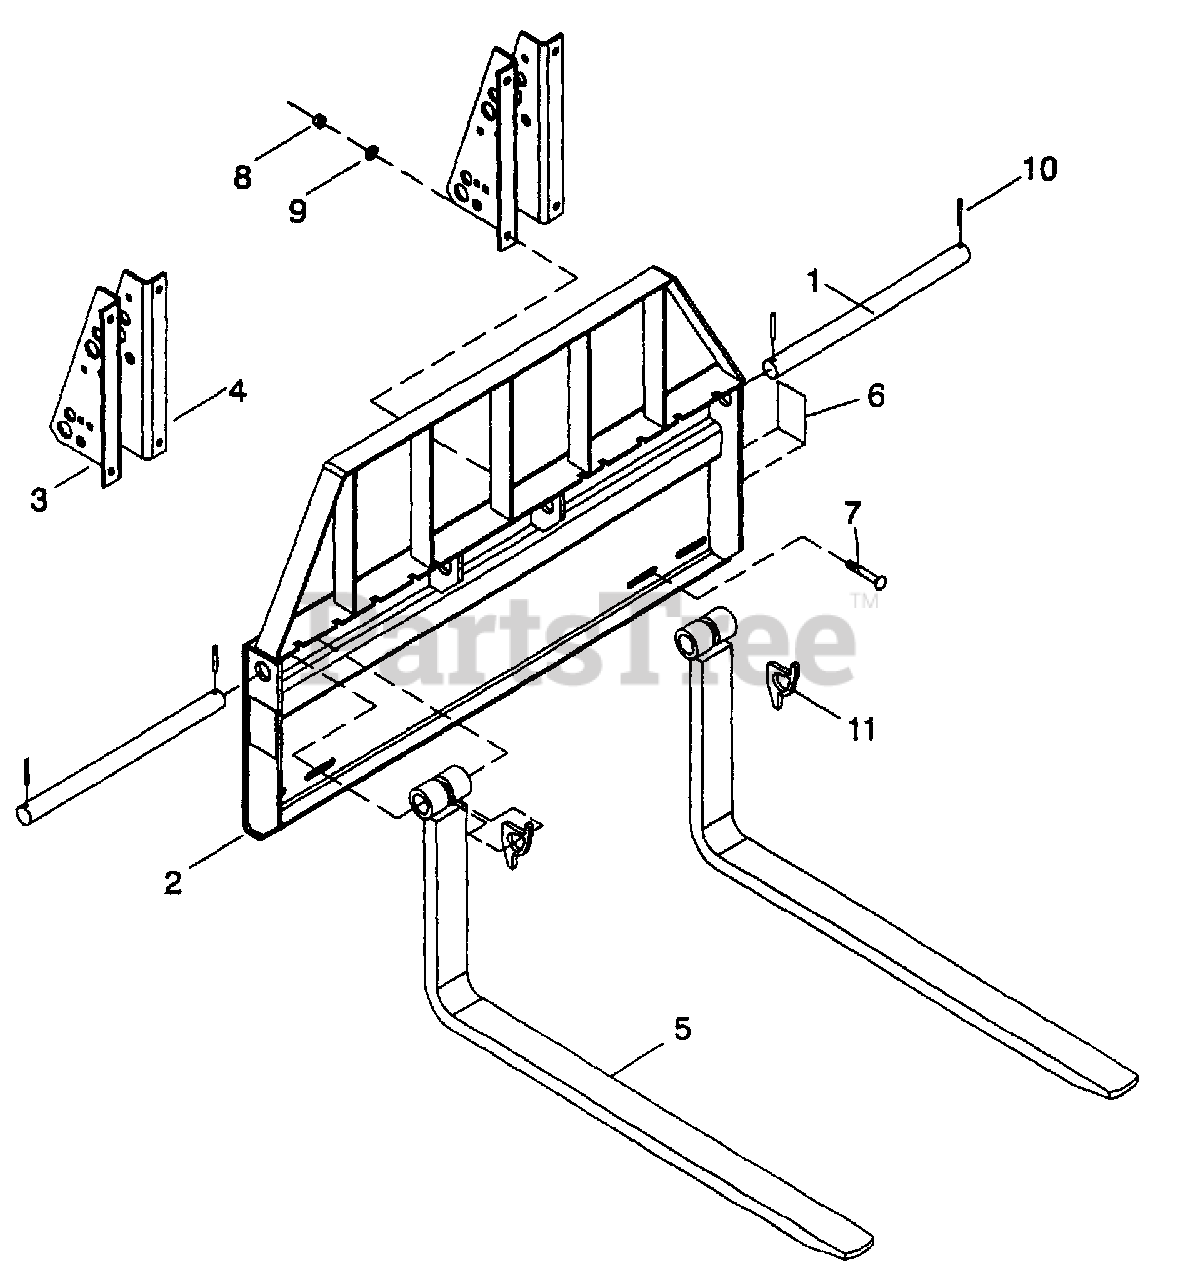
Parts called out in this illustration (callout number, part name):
2	Back plate
3	Attachment angle, right hand
4	Attachment angle, left hand
6	Warning decal
7	1/2 NC x 1-1/4 Carriage bolt plated
8	1/2 NC Hex nut plated
9	1/2 Standard lockwasher
10	1/4 x 2 Roll pin
11	Tooth lock
